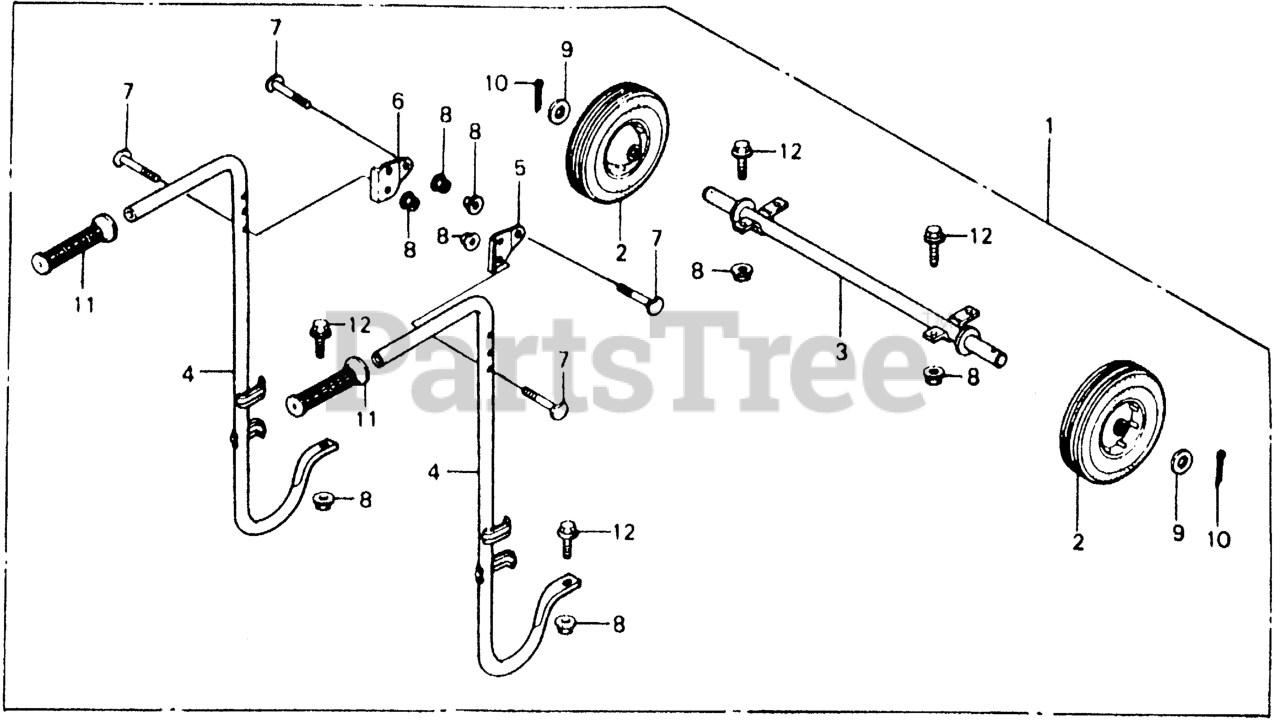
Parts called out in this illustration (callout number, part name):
1	WHEEL KIT (2-WHEELS)
2	WHEEL (GLEASON 10"X2.75"=254X70)
3	SHAFT, WHEEL
4	HANDLE, CARRY
5	HOLDER, R. HANDLE
6	HOLDER, L. HANDLE
7	BOLT, HANDLE HOLDER (8X36)
8	NUT, FLANGE (8MM)
9	WASHER, PLAIN (20MM)
10	PIN, SPLIT (4.0X28)
10	PIN, COTTER (4.0X30)
11	GRIP D, R. HANDLE (BOTH SIDES)
12	BOLT, FLANGE (8X16) Use from Engine SN 1000016.
